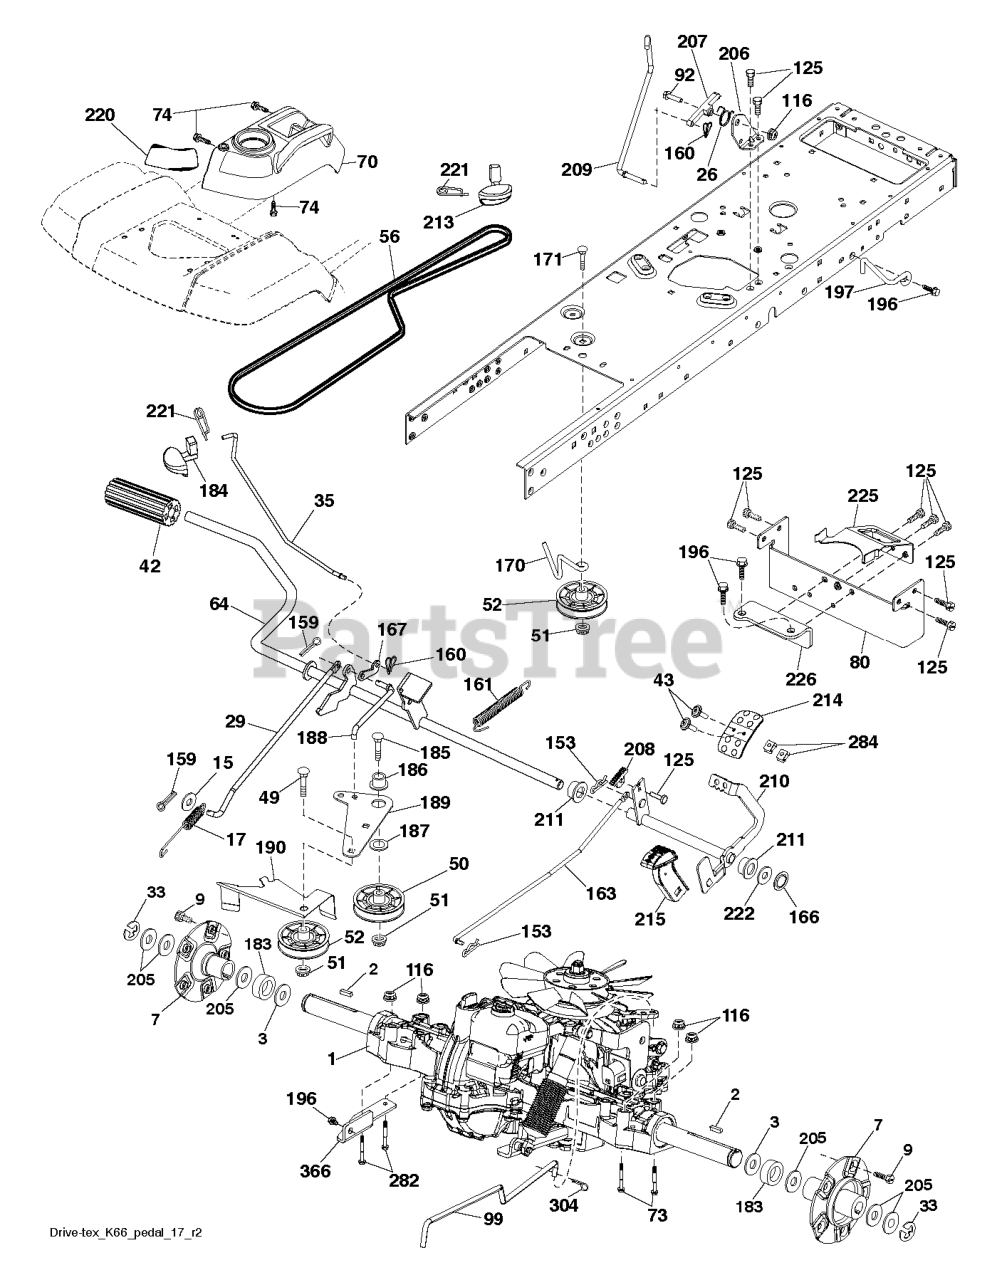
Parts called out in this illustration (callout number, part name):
2	KEY, 1/4 SQ X 1 1/4
7	HUB.PNT.GT.PM.1IN.AXLE.E-DIP
9	HUB BOLT
15	WASHER
17	SPRING.BRAKE.K46
26	SPRING.RETURN.CRUISE
29	ROD.BRAKE.K66
33	E RING HYT
35	ROD .BRAKE. PARKING. GT. HUSQ.
42	PEDAL COVER T
43	SCREW.MACHINE.CR.1/4-20
50	IDLER.FLAT.910.OFFSET
51	NUT LOCK FLG 3/8-16 UNC
52	IDLER.V-GROOVE.910.OFFSET
64	SHAFT.ASM.PEDAL.BRK.CNTR
70	CONSOLE.ASM.RH.GT.FC.HUSQ
73	BOLT HEX 5/16-18 GR 5
74	SCREW.HI-LO.CONSOLE
80	TORQUE.STRAP.PNT.BLACK
92	BOLT
99	ROD.BYPASS.K66
116	NUT LOCK HEX FLANGE 5/16-18
125	SCREW
153	RETAINER M
159	COTTER PIN
160	RETAINER CLIP
161	SPRING, RETURN LT
163	ROD.PEDAL.CONTROL
166	NUT.PUSH.625
167	LATCH.BRAKE.SPRING
170	KEEPER.V-IDLER.CENTER.
171	BOLT
183	SPACER.SPLIT.1.000ID X 1.500
184	HANDLE.PARKING.BRAKE.H (BLK)
186	SPACER.RETAINER
187	WASHER 12/32X2X10GA
188	LINK.CLUTCH.GROUND DRIVE.LONG
189	BELLCRANK.GROUND.DRIVE.TEX.
190	KEEPER.BELLCRANK.DRIVE
196	SCREW 3/8-16X1
197	CLUTCH.ANTIROTATION.WIREFORM.
206	BRACKET.MOUNT.CRUISE.LATCH
207	LATCH.CONTROL.CRUISE.TEX
208	GEAR.SECTOR.CONTROL.CR
209	ROD.CONTROL.CRUISE.GT.
210	ROCKER.ASM.PEDAL.CONTR
211	BEARING.NYLON
213	KNOB.CONTROL.CRUSIE.HU
214	PEDAL.FORWARD.HUSQVARNA.DEALER
215	PEDAL.COVER.REVERSE.CRD.X428BK
220	REFLECTOR.RH.TEX GT
221	RETAINER.SPRING.CLIP.H
222	WASHER 21/32 X 1-1/4 X 10 GA.
225	KEEPER.BELT.TRANSAXLE.K66
226	BRACKET.MOUNT.TORQUE.K66.TG
282	BOLT HEX FLGHD 5/16-18X3 GR. 5
284	NUT.U-CHNL.1/4-20.550DP.350PNL
304	HAIRPIN.SOFT.ZINC.059X1.125
366	BRACKET.REINFORCEMENT
